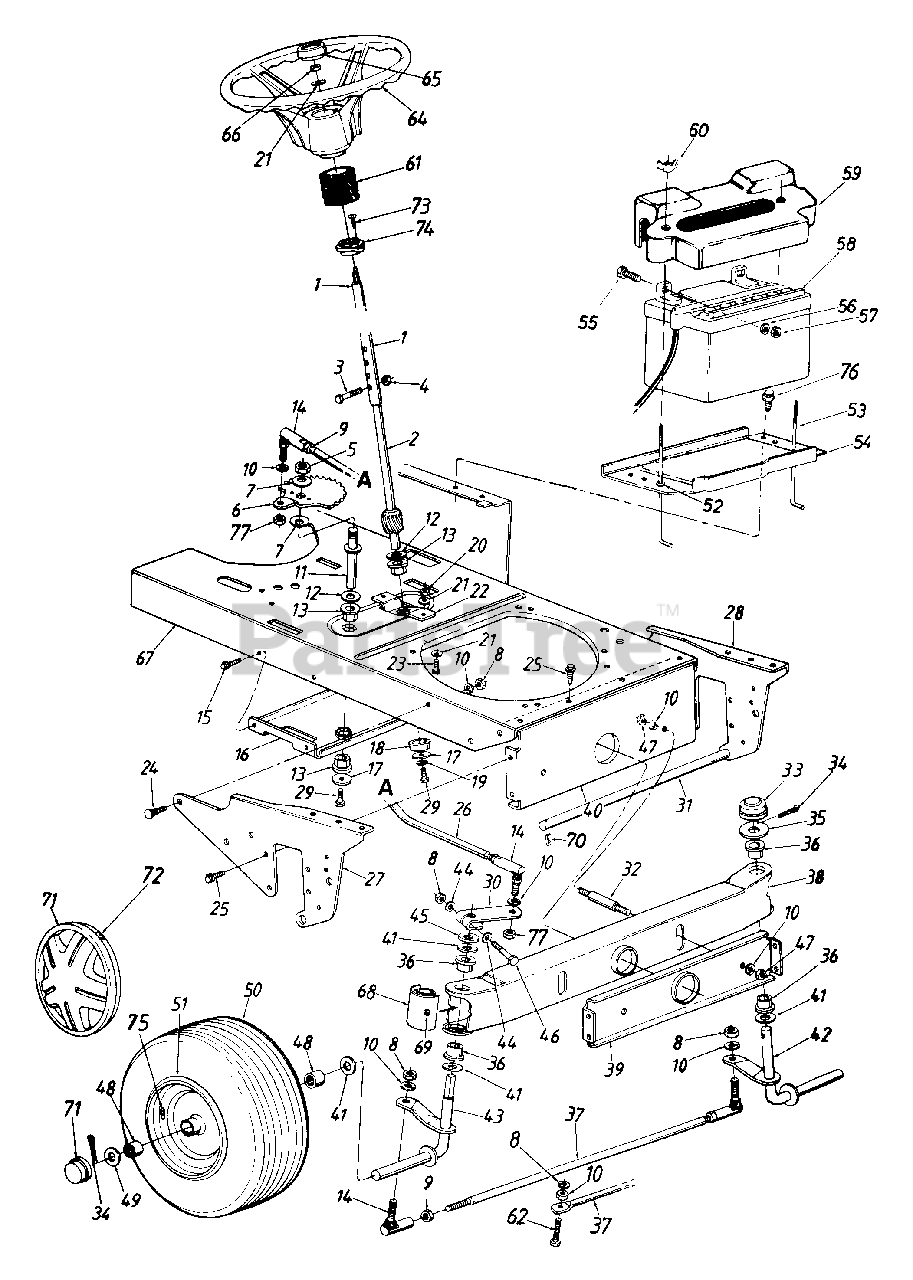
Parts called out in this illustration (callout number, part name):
1	Steering Column Ass'y.
2	Lower Steering Shaft
3	Hex Bolt 1/4-20 x 1.31" Lg.
4	Hex L-Nut 1/4-20 Thd.
5	Hex Jam Nut 5/8-18 Thd.
6	Steering Gear Segment
7	Bell-Wash. 5/8" I D. x 1.25" O.D.
8	Hex Nut 3/8-24 Thd.
9	Hex Jam Nut 3/8-24 Thd.
10	L-Wash. 3/8" I.D.
11	Steering Gear Segment Shaft
12	Fl-Wash. 64" I.D. x 1.24" O.D.
13	Hex Flange Brg. .63" I.D.
14	Ball Joint Ass'y.
15	Hex Wash. Hd. TT-Tap Scr. 1/4-20 x .5" Lg.
16	Deck Idler Support Brkt.
17	Fl-Wash. .33" I.D. x 1.25" O.D.
18	Spacer .985" I.D. x 1.25" O.D.
19	L-Wash. 5/16" I.D.
20	Hex Nut 5/16-24 Thd.
21	Bell-Wash. .345" I.D. x .88" O.D.
24	Ribbed Neck Bolt 3/8-24 x .8" Lg.
25	Hex Wash. TT-Tap Scr. 5/16-18 x .62" Lg.
26	Steering Drag Link
27	Pivot Bar Side Plate - R.H.
28	Pivot Bar Side Plate - L.H.
29	Hex Bolt 5/16-18 x .62" Lg.
30	Steering Arm
31	Deck Connecting Rod
32	Pivot Bar Shld. Bolt 3/8-16 x 5/8" Lg.
33	Cap
34	Cotter Pin 5/32" Dia.
35	Flat Washer
36	Flange Brg. .757" I.D.
37	Tie Rod 20.25" Lg. (Adjustable)
38	Pivot Bar Assy.
41	Fl-Wash. .76" I.D. x 1.49" O.D.
42	Front Axle Ass'y. - L.H.
43	Front Axle Ass'y. - R.H.
44	Bowed Washer
45	Spacer .755" I.D. x 1.25" O.D.
46	Hex Bolt 3/8-24 x 2.25" Lg.
47	Hex Nut 3/8-16 Thd
48	Bearing
49	Fl-Wash. .71" I.D. x 1.5" O.D.
51	Rim Only
52	Push Nut
53	Battery Hold Down Rod
54	Battery Plate
56	L-Wash. 1/4" I.D.
57	Hex Nut 1/4-20 Thd.
58	Battery (275 Cold Crank Amps)
59	Battery Cover
60	Wing Nut Plastic 1/4-20 Thd.
61	Steering Bellow
62	Hex Bolt 3/8-24 x 1.5" Lg. (Gr. 5)
64	Steering Wheel (3 Spoke)
65	Steering Wheel Cap
66	Hex L-Nut 5/16-24 Thd.
69	Grease Fittings
70	Internal Cotter Pin
71	Hub Cap
72	Spring Clip
73	Oval Hd. Cr.-Sunk Scr. #10 x 5/8" Lg.
74	Flange Brg. .89" I.D. x 1.36" O.D.
75	Air Valve
76	Hex AB-Tap Scr. 1/4 x .62" Lg.
77	Hex Jam L-Nut 3/8-24 Thd.
